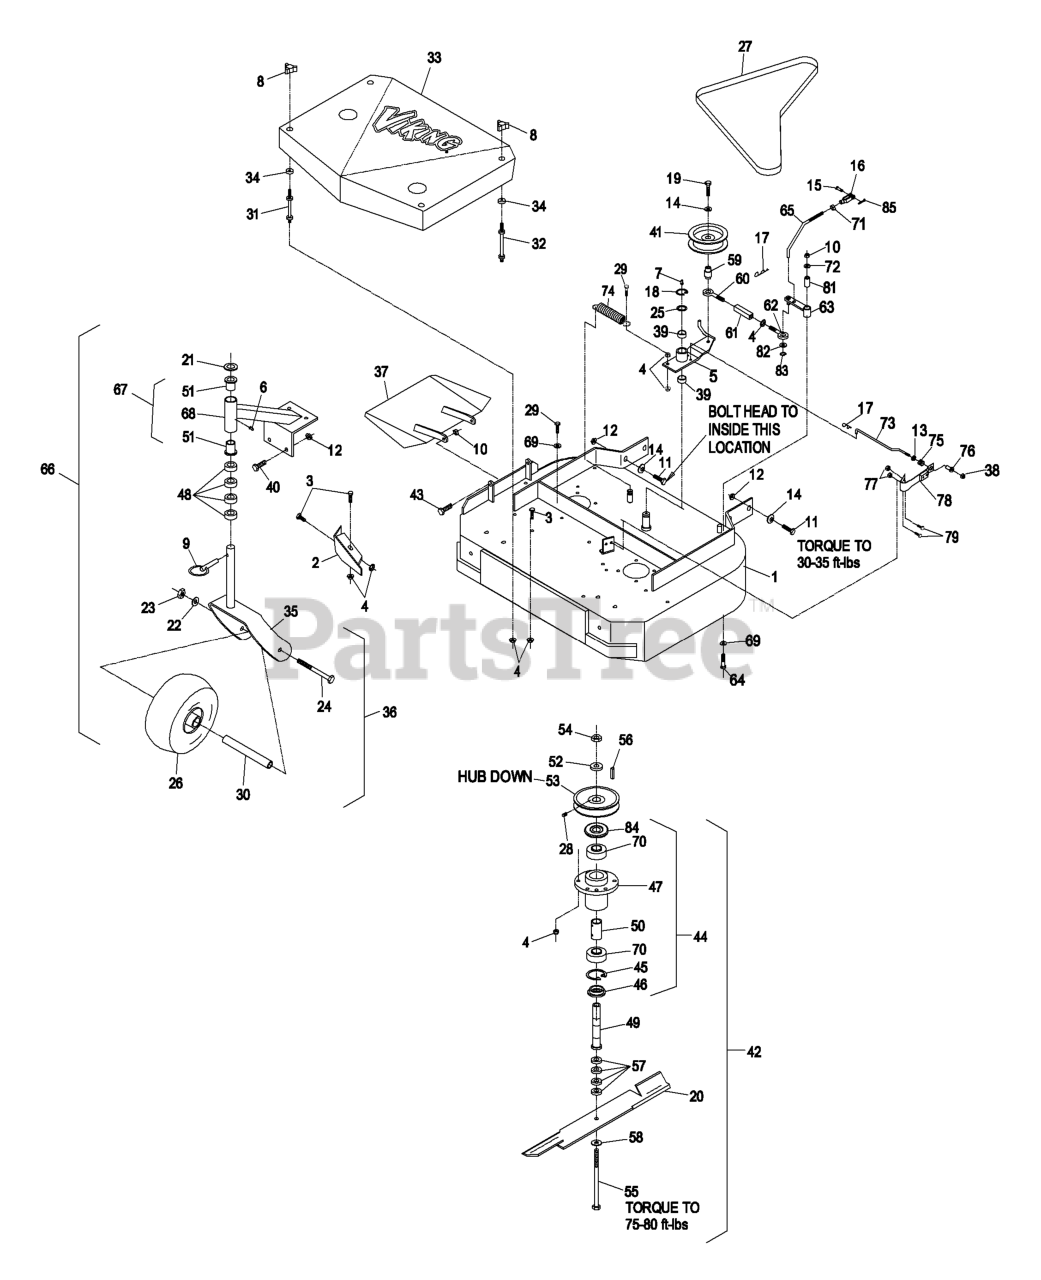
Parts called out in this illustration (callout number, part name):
1	ASM,DECK 36 RIGID
2	BAFFLE-DOGLEG
3	SCREW-HH
6	FITTING-GREASE
7	FITTING-GREASE
8	KNOB-3 PRONG
10	NUT-LOCK, NI
11	SCREW-HH
12	NUT-HHF, WHIZ
13	RING-PUSH ON
14	WASHER-BELLEVILLE
15	PIN-CLEVIS
16	YOKE-ADJUSTABLE
17	PIN-COTTER
18	RING-RETAINING, EXT
19	SCREW-HH
21	WASHER-FLAT
22	WASHER-LOCK
23	NUT-HH
24	SCREW-HH
25	WASHER-SPINDLE
27	BELT,BLADE VIKING HYD 36
28	SCREW-SET
29	SCREW-HH
30	SPACER FRONT CASTER
31	STUD-SHIELD, BELT (SHORT)
32	STUD-SHIELD, BELT (LONG)
36	ASM,CASTER/WHEEL
37	WLD,CHUTE 36 RIGID
38	NUT-LOCK, NI
39	SLEEVE-BEARING
40	SCREW-HH
43	SCREW-HH
45	RING-SNAP
46	SPACER-GUARD, BOTTOM
48	SPACER-CASTER
49	TUBE-SPINDLE, SHORT
50	SPACER-BEARING
51	BEARING-FLANGED
52	WASHER-RETAINER, SHEAVE
53	SHEAVE
54	NUT-HEX
55	SCREW-CAP, HH
58	WASHER-SPRING
59	BUSHING-ENGAGEMENT
60	EYEBOLT-THREAD, LH
61	BODY-TURNBUCKLE
62	EYEBOLT-THREAD, RH
63	ARM-ASSIST, 32/36
64	SCREW-HH
65	ARM-LINKAGE, ASSIST
67	ASM,CSTR SUPPORT W/WEIGHT
69	WASHER-SPRING
70	BEARING-JACKSHAFT
71	NUT-HEX
72	WASHER-FLAT
73	ROD-BRAKE
74	SPRING-EXTENSION
75	SPRING-COMPRESSION
76	SPACER-FLANGED
77	NUT-LOCK, NI
78	PAD AND SPRING ASM
79	SCREW-HH
81	TUBE-PIVOT
82	WASHER-PLAIN
83	RING-RETAINING, EXT
84	GUARD-BEARING, TOP
85	PIN-COTTER
86	KIT, SP CASTER WHEEL REPL
